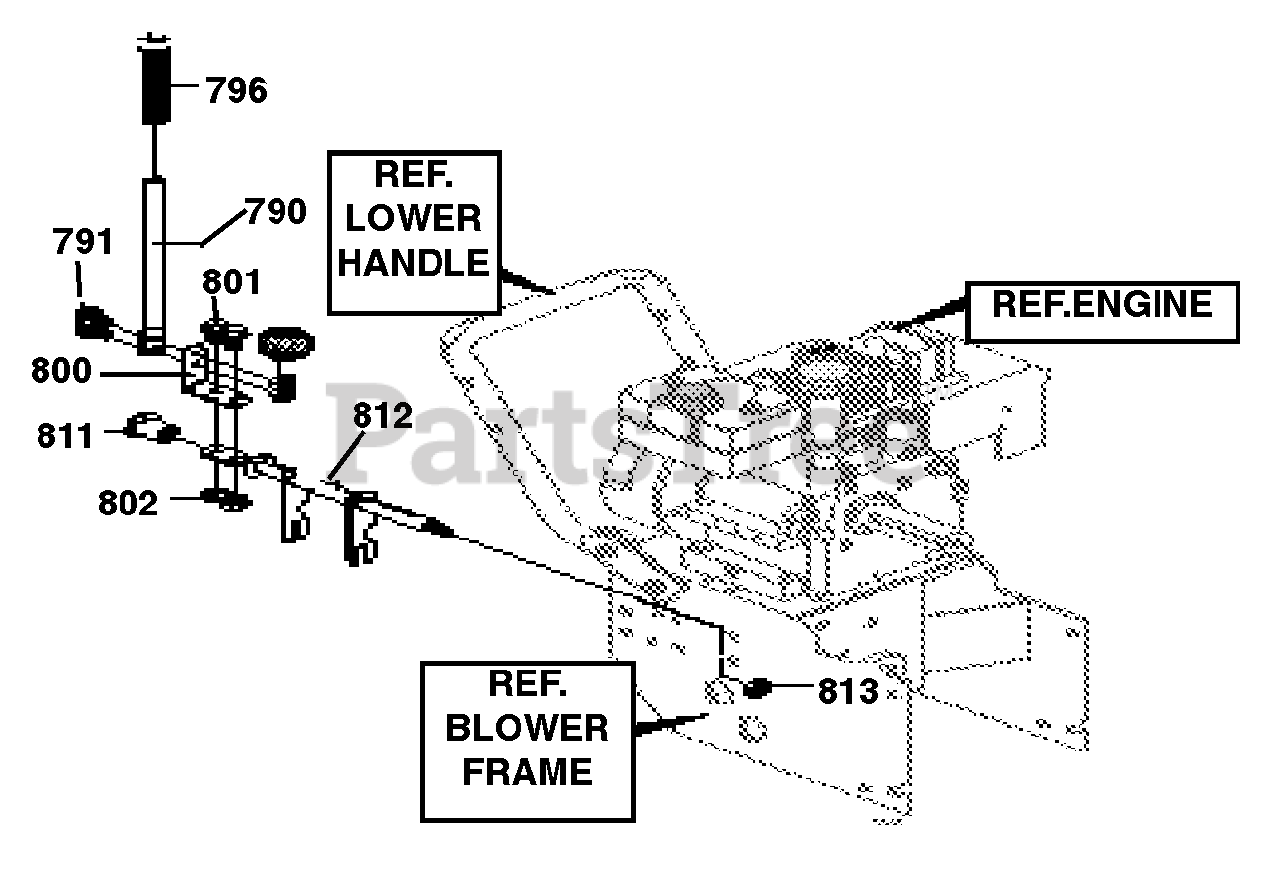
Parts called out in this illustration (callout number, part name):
790	ROD, SHIFT
791	SCREW, 1/4-20 X .75
792	NUT, 1/4-20 RGHXCTRLK
796	KNOB, SLIP
800	LEVER, SPRING
801	SCREW, 1/4-20 X .75
802	NUT, 1/4-20 RGHXCTRLK
811	BEARING, FLANGE
812	ROD, ASSY YOKE
813	NUT, 3/8-16 RGHXCTRLK REF
